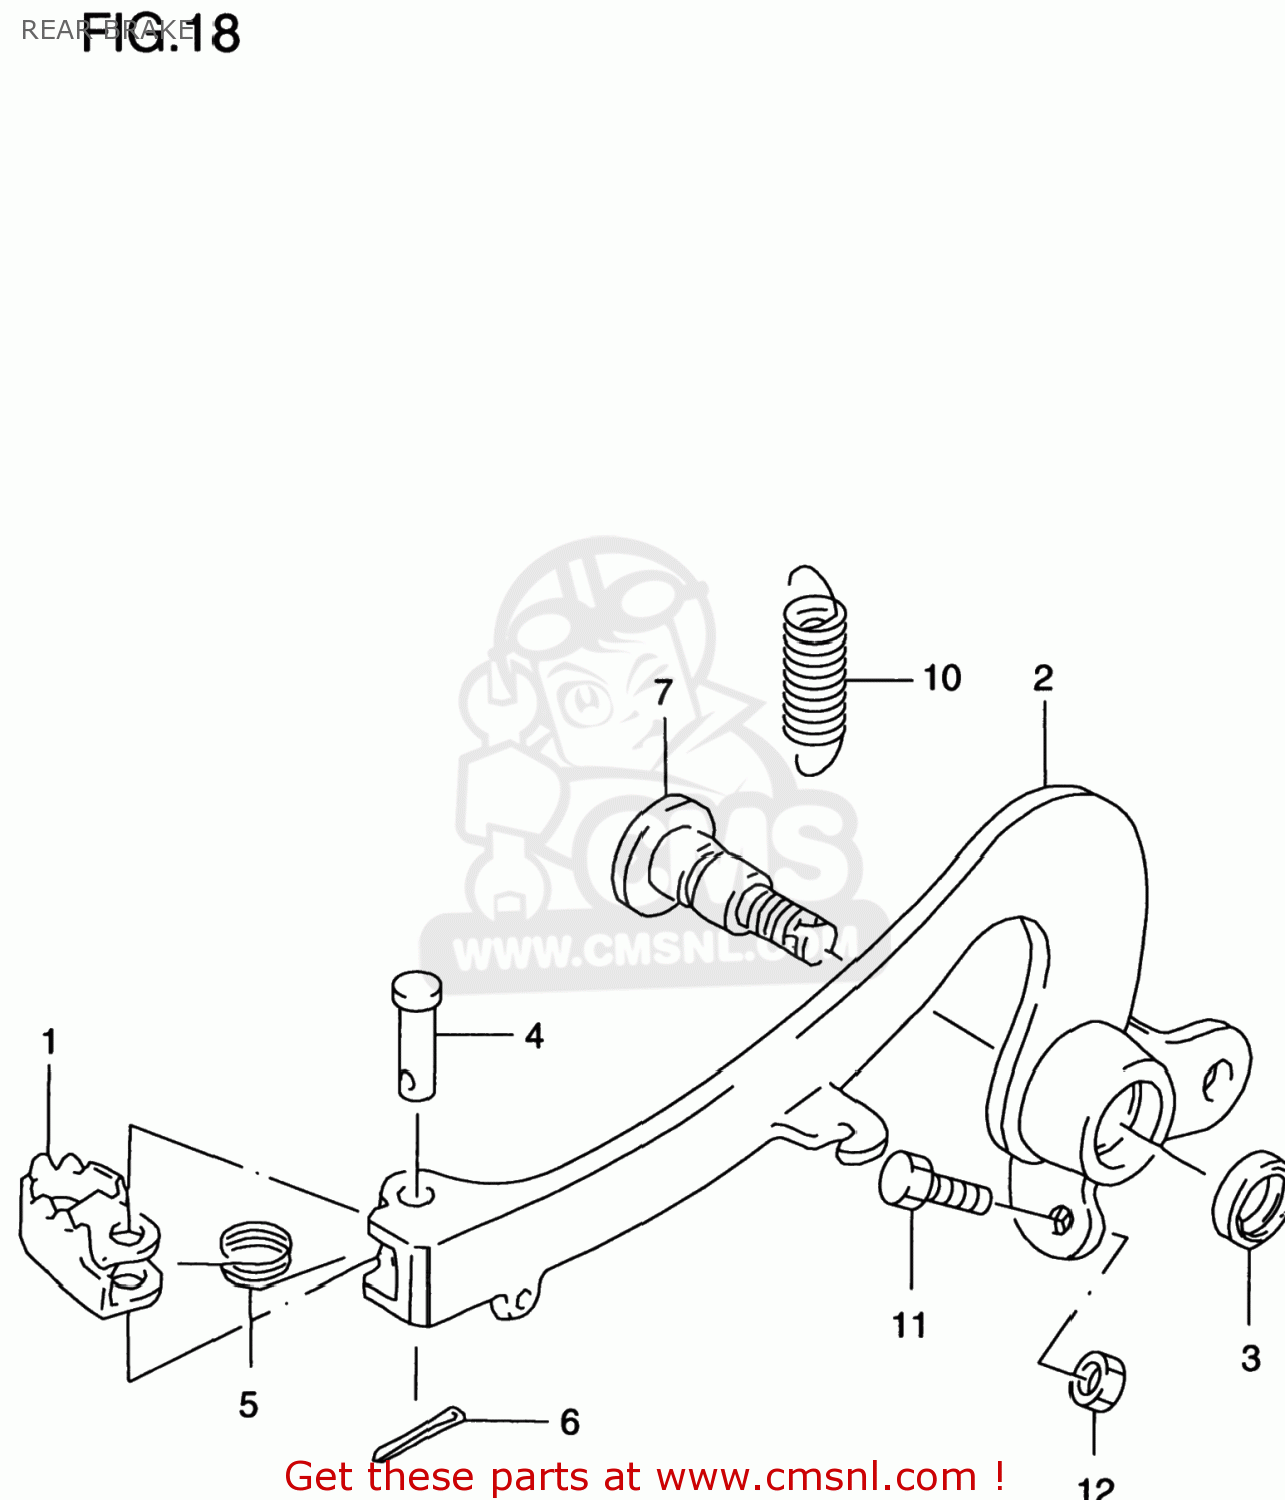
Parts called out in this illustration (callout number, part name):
1	PEDAL,BRAKE
2	ARM,BRAKE PEDAL
3	SEAL,OIL(15X21X3)
4	PIN(6X23.5)
5	SPRING
6	PIN
7	SHAFT,BRAKE PEDAL
8	WASHER
9	PIN 20X20
10	SPRING
11	BOLT(6X23)
12	NUT 6MM
